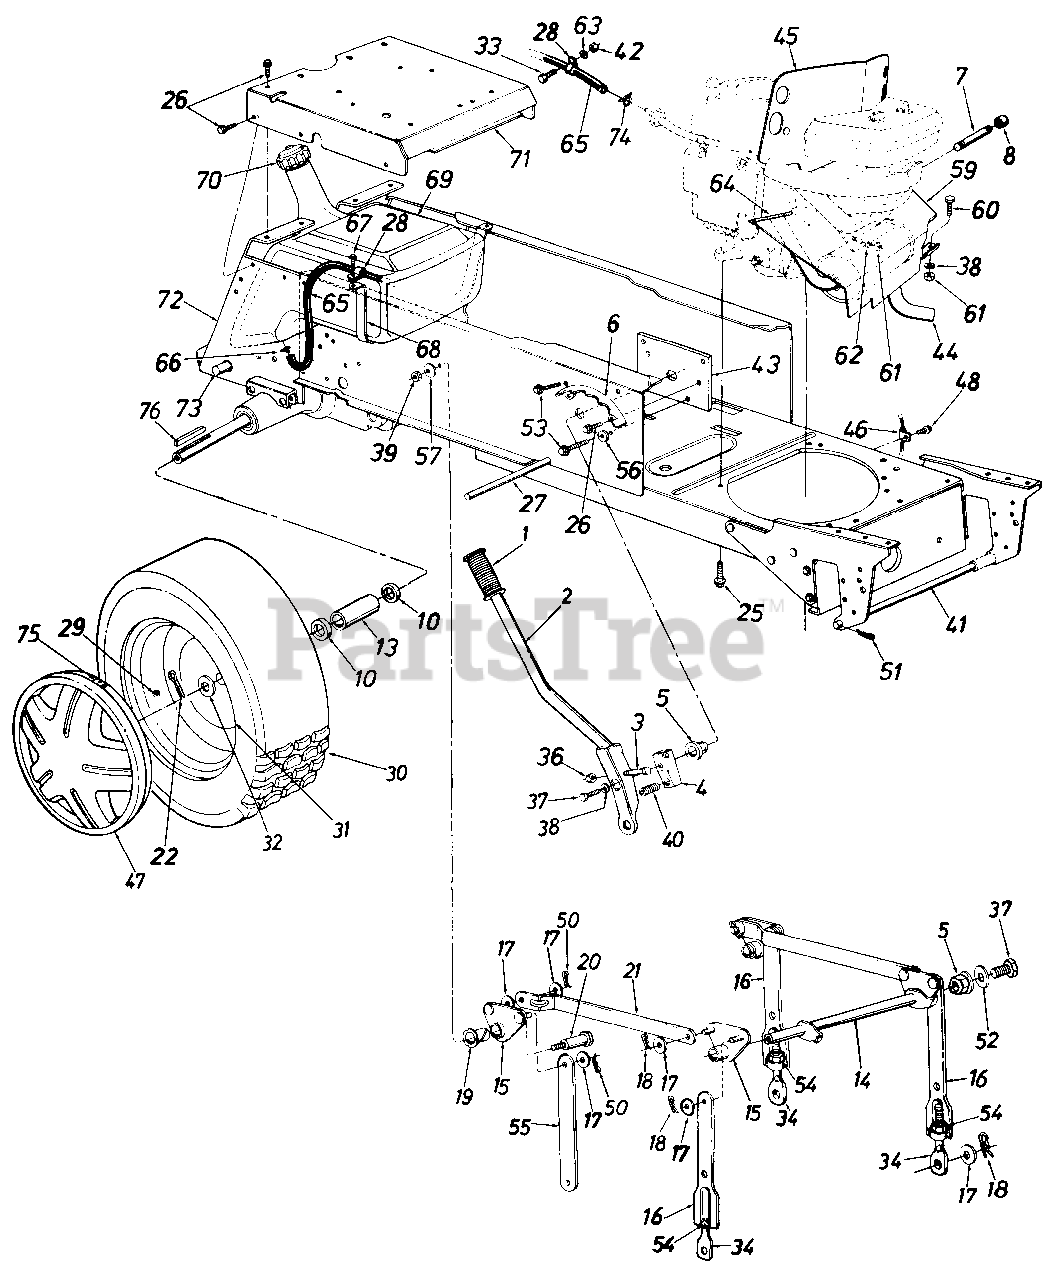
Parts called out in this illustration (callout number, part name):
1	Grip
2	Lift Handle Ass'y.
3	Hex Bolt 5/16-18 x 1.5" Lg.
4	Lift Shaft Drive
5	Plastic Hex Brg. 5/8" I.D.
8	Pipe Cap 3/8-18 Npt.
10	Fl-Wash. 1.03" I.D. x 1.62" O.D.
13	Spacer 1.0" I.D. x 1.25" O.D.
14	Lift Shaft Ass'y.
15	Lift Pivot Brkt. Ass'y.
17	Fl-Wash. 1/2" I.D. x 1.00" O.D. x .090"
18	Hairpin Cotter
19	Nyliner 5/8" I.D. x .88" Lg.
20	Shld. Bolt 5/8" Dia. x .96" Lg. 3/8-16
25	Hex Wash. Hd. Scr. 3/8-16 x 1.25" Lg.
26	Hex Thd. Rolling Scr. 5/16-18 x.75" Lg.
27	Running Board Rod
28	Clamp
29	Air Valve
33	Hex Bolt 1/4-20 x .62" Lg.
34	Eye Bolt Adj. Link 1/2-13 Thd.
36	Hex Cent. L-Nut 5/16-18 Thd.
37	Hex Scr. 5/16-24 x .62" Lg.
38	L-Wash. 5/16" I.D.
39	Hex Top L-Nut 3/8-16 Thd.
40	Compression Spring
41	Deck Connecting Rod
42	Hex Nut 1/4-20 Thd.
45	Heat Shield
46	Mounting Clamp
47	Hubcap
48	Hex Wash. Hd. TT-Tap Scr. 1/4-20 x .5" Lg.
50	Cotter Pin .09 Dia. x 1.01" Lg.
51	Int. Cotter Pin
52	Flat Wash. .34" I.D. x 1.12" O.D. x .125"
53	Hex Wash. Hd. AB-Tap Scr. 5/16-24 x .5" Lg.
54	Hex Nut 1/2-13 Thd.
56	Fl-Wash. .344" I.D.
57	Bell-Wash. .4" I.D. x 1.13" O.D.
59	Front Heat Shield
60	Hex Bolt 5/16-18 x .75" Lg.
61	Hex Nut 5/16-18 Thd.
62	L-Wash. 5/16" I.D.
63	L-Wash. 1/4" I.D.
64	Trim Strip 10" Lg.
65	Fuel Line 50" Lg.
66	Hose Clamp
67	Hex AB-Tap Scr. 1/4 x .62" Lg.
68	Fuel Tank Strap
69	Gas Tank
70	Gas Gauge
71	Seat Plate
74	Hose Clamp
75	Spring Clip
76	Sq. Key 1/4" x 3" Lg.
